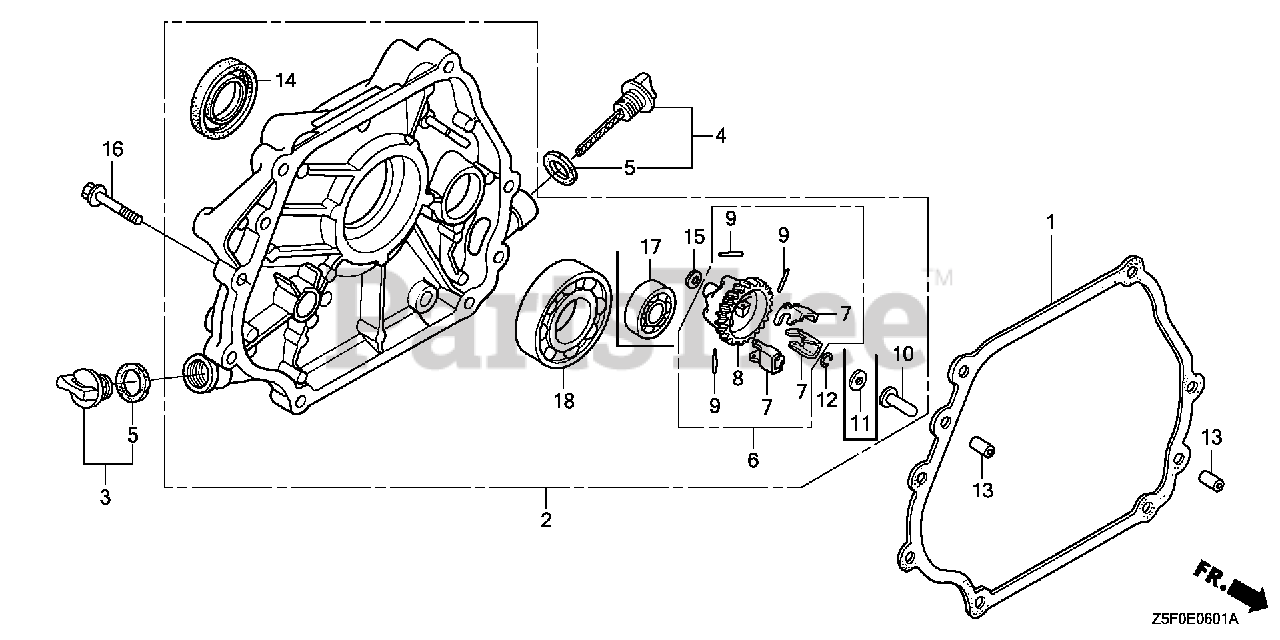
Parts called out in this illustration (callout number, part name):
1	GASKET, CASE COVER
2	COVER ASSY., CRANKCASE
3	CAP ASSY., OIL FILLER
4	CAP ASSY., OIL FILLER
5	GASKET, OIL FILLER CAP
6	GOVERNOR ASSY.
7	WEIGHT, GOVERNOR
8	HOLDER, GOVERNOR WEIGHT
9	PIN, GOVERNOR WEIGHT
10	SLIDER, GOVERNOR
12	CLIP, GOVERNOR HOLDER
13	PIN, DOWEL (8X12)
14	OIL SEAL (30X45X8)
14	OIL SEAL (30X46X8)
15	WASHER, PLAIN (6MM)
16	BOLT, FLANGE (8X35)
18	BEARING, RADIAL BALL (6206)
